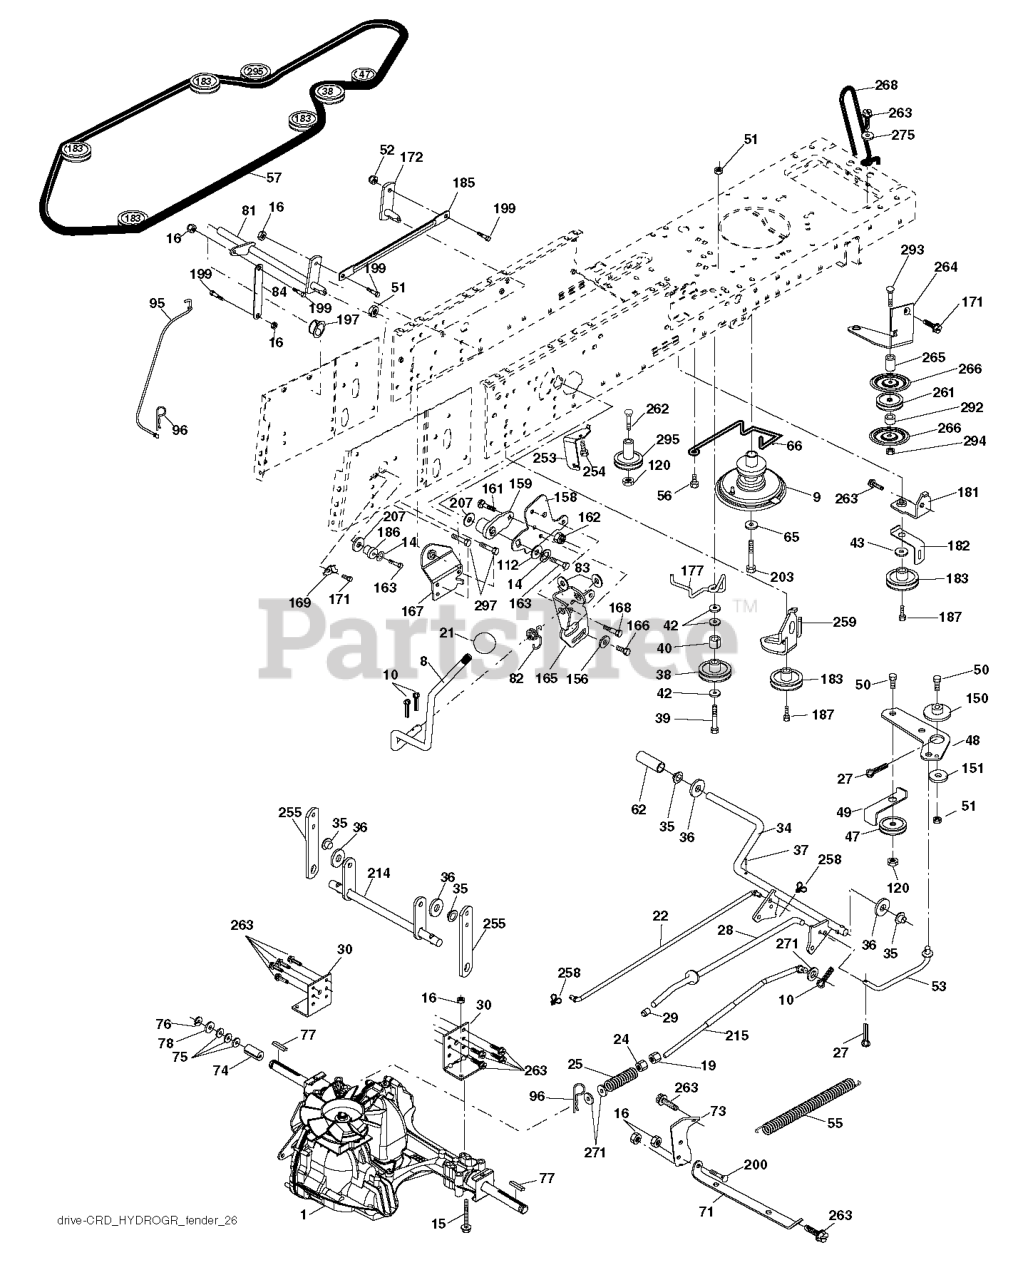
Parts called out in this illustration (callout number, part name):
1	Husqvarna TBD
2	SPRING,BRAKE RETURN
3	PULLEY
4	RETAINING RING LT
5	STRAP TORQUE
6	SCREW 5/16"
8	ROD SHIFT FENDER ADJUST LT
10	PIN COTTER
11	WASH-SHFT PLT LT
13	BOLT 1/4-28X3/4
14	LOCKWASHER
15	BOLT HEX 5/16-18 GR 5
16	NUT.71038.31-18.HEX.NYLOCK
18	BOLT
19	NUT
21	KNOB T (1/2-HOLE)
22	ROD
24	NUT
25	SPRING ROD LT
26	WASHER
27	COTTER PIN
28	ROD, PARKING BRAKE
29	PLUNGER CAP
30	Transaxle Bracket
34	SHAFT, FOOT PEDAL
35	BEARING.NYLON
36	WASHER LT
37	DRIVE PIN
38	PULLEY.FLAT
42	WASHER
43	WASHER T
47	IDLER PULLEY
48	BELLCRANK, CLUTCH
49	RETAIN BELT
50	BOLT.3/8-16X1.50
53	LINK.CLUTCH.7.66.2005
55	SPRING, RETURN LT
56	SCREW.3/8-16
57	V-BELT.KEV.111"
62	PEDAL COVER T
65	LOCKWASHER
66	KEEPER BELT ENGINE
74	SPACER AXLE
77	SQUARE KEY
79	KEY.WOODRUFF
82	SHIFT SPRING
83	WASHER
96	RETAINER M
112	WASHER LT
120	NUT LOCK FLG 3/8-16 UNC
150	BUSHING.BELLCRANK.GRD.DR
151	WASHER 12/32X2X10GA
156	WASHER.SRRTD.5/16
158	BRACKET
159	RB HUB.SHIFT
161	BOLT
162	NUT.CROWNLOCK.1/4
163	BOLT
165	RP BRACKET
166	CAPSCREW.HXHD.FLG.5/16-18X.625
167	BRACKET.SUPT.SHIFT.CRD
168	BOLT.SHOULDER.5/16-18X
171	SCREW LT
172	SHAFT
181	BRACKET
182	BELT GUIDE
183	PULLEY.V-IDLER.
187	BOLT.5/16-18X1.25
203	BOLT.HEX.7/16-20 X 5
207	WASHER NYL
214	LEVER
254	SCREW 3/8-16X1
255	SHAFT
258	CLIP RETAINER
261	FLAT IDLER PULLEY
263	SCREW, 3/8-16X3/4
264	BRACKET.IDLER.CHASS.NORAM.2010
265	SPACER
266	PROTECTOR
268	GUARD MUFFLER
275	WASHER
293	BOLT.RDHD SQNK 3/8-16 X 3-1/2
294	Hex Nut, 3/8-16
295	PULLEY IDLER COMPOSITE
297	SCREW LT.3/8-46X5/8
